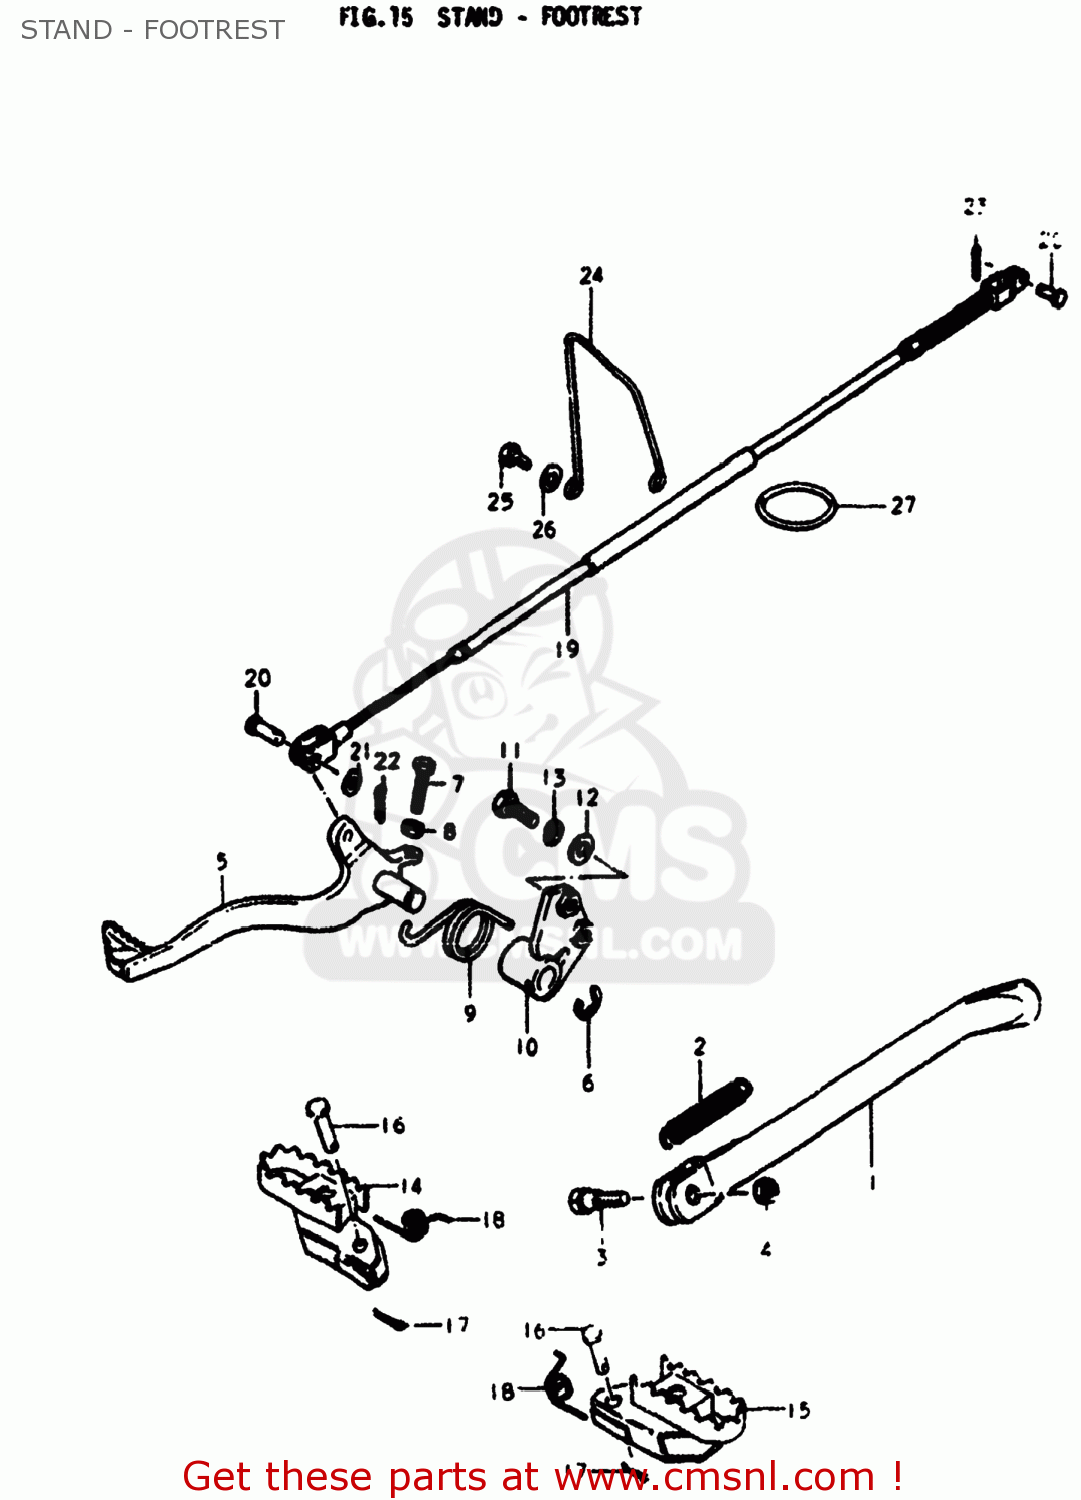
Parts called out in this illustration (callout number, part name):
1	STAND,PROP
2	SPRING
3	BOLT(10X30)
4	NUT
5	PEDAL,BRAKE
6	E RING
7	BOLT(6X23)
8	NUT
9	SPRING
10	VALVE ASSEMBLY,WHEEL RIM
11	BOLT
12	WASHER
13	LOCK WASHER
14	FOOTREST,FRONT
15	FOOTREST
16	PIN
17	PIN 20X20
18	SPRING
19	CABLE,RR BRAKE
20	PIN(L:17.5)
21	WASHER
22	PIN 20X20
23	PIN
24	GUIDE,CABLE
25	BOLT
26	WASHER
27	O RING,RR BRAKE CABLE
